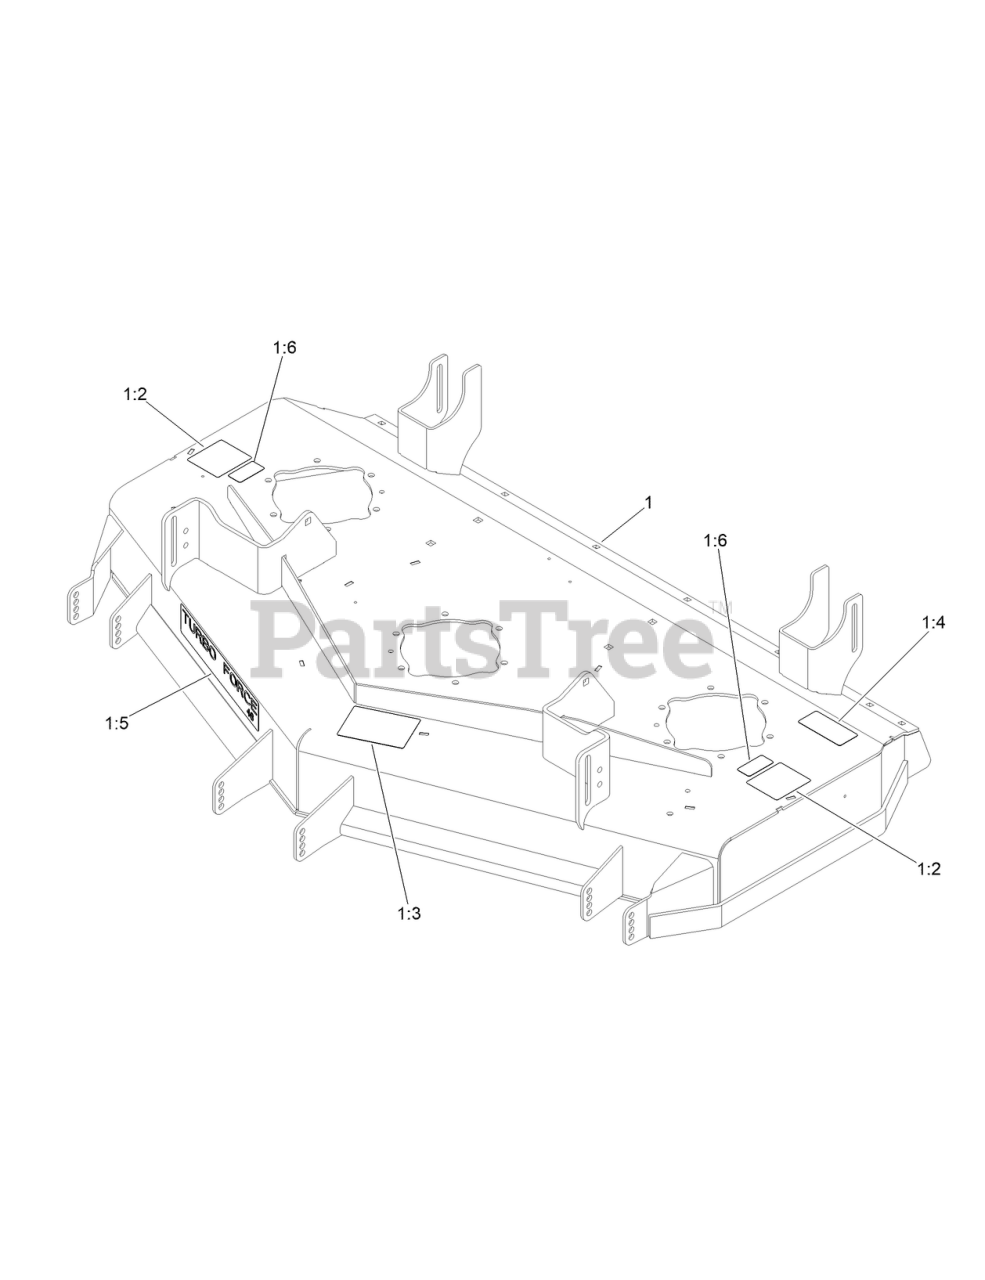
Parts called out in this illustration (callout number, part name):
1:2	DECAL-WARNING, DECK
1:3	DECAL-SCALP, ANTI
1:4	DECAL-DANGER
1:6	DECAL-NO SPRAY
